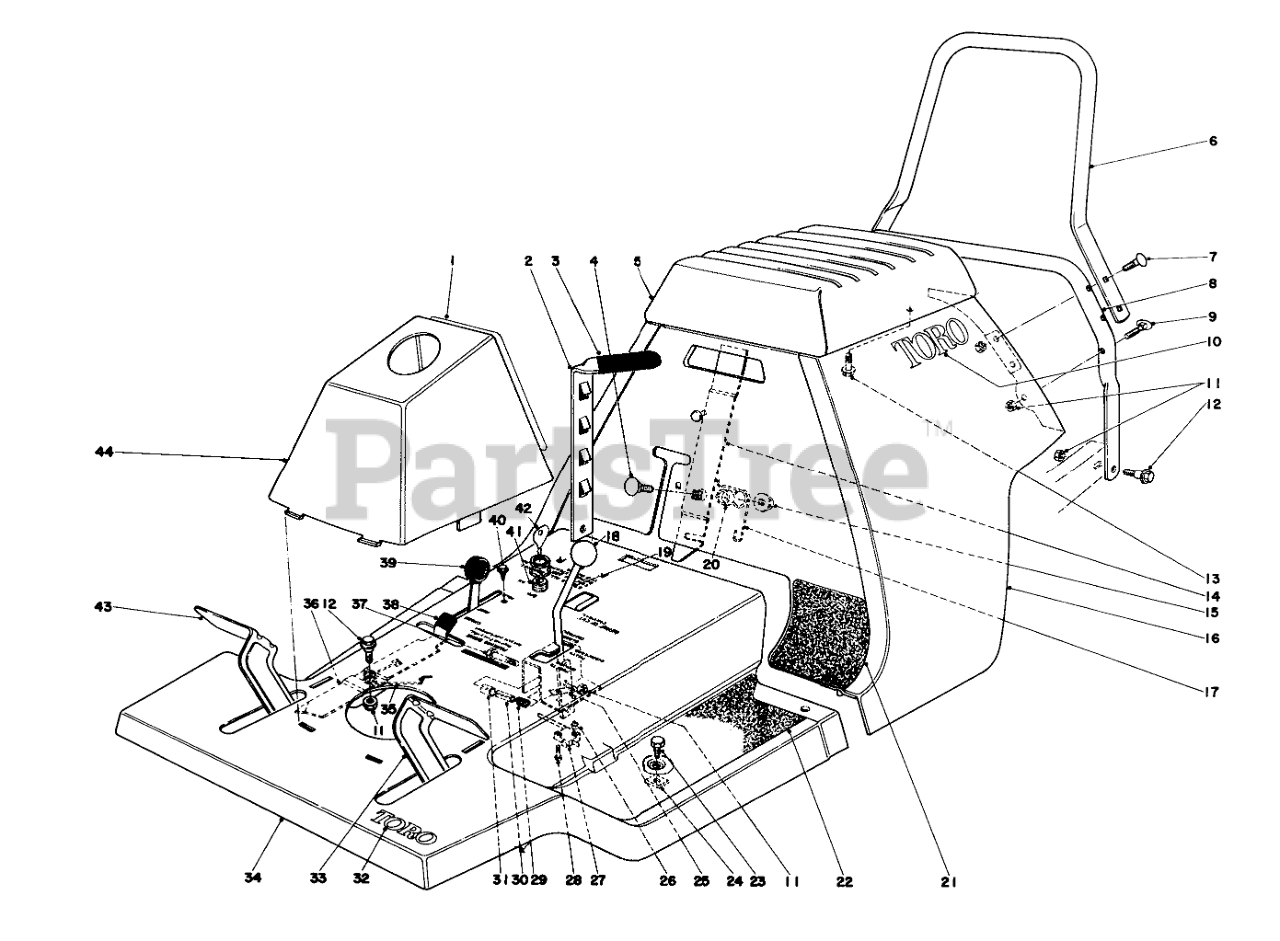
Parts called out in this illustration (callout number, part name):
1	Decal Tower
2	Lift-Vertical
3	Grip Handle
4	BOLT-CARR
6	Handle Upper
7	SCREW-CARR
8	Handle Lower
9	HANDLE SCREW
10	Decal
11	NUT-LOCK, CONE
12	SCREW-SHOULDER
13	SCREW-HHF
14	Handle Latch
15	NUT-HF
16	Rear Body
17	Latch Return Spring
18	KNOB-CONTROL
19	Deck Engagement Lever
20	Spacer
21	Heel Pad L.H.
22	Foot Tread L.H.
23	SCREW-HH
24	NUT-TINNERMAN
25	NUT-SPEED
26	Spacer
27	MICRO SWITCH
28	SCREW-PPH
29	Spring
30	Spacer Split
31	Spacer
32	DECAL
33	Clutch Pedal
34	Front Body
35	SPRING-PARKING BRAKE
36	Parking Brake
37	SCREW-HH
38	TIP-PARKING BRAKE
39	Throttle Control
40	8X1/2 SELF TAP SCREW
41	ON-OFF SWITCH 21-8-468
42	Key
43	Brake Pedal
44	Tower
